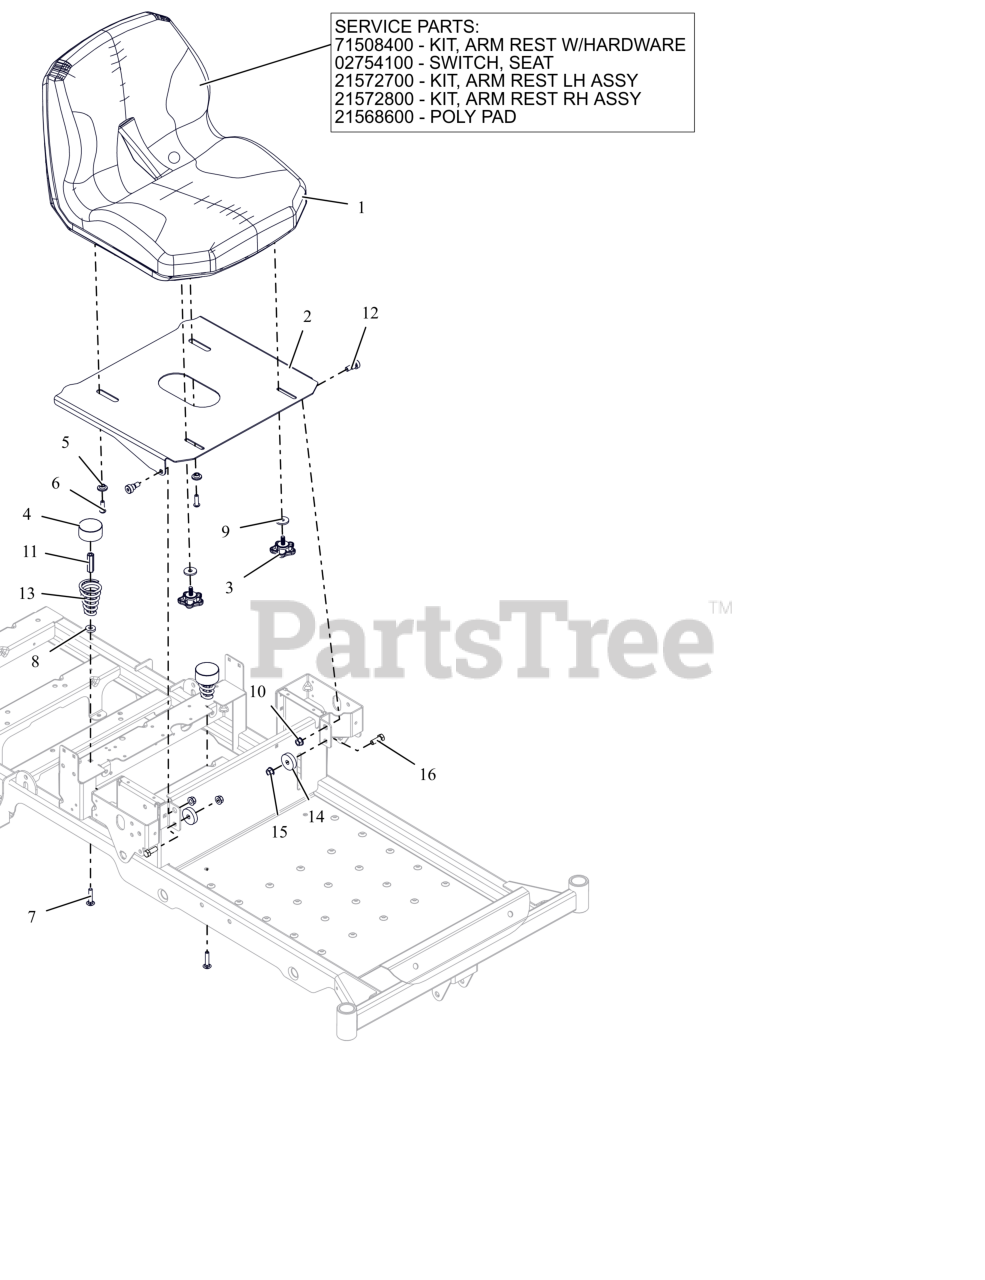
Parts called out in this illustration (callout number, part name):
1	SEAT, EDGE 2020
1	KIT, ARMREST - EDGE
1	SWITCH- SNAP MTG N.O.
1	KIT, ARM REST LH ASSY - PADDED
1	KIT, ARM REST RH ASSY - PADDED
1	POLY PAD
2	PLATE, SEAT (ORANGE)
3	KNOB, WING STUDDED
4	HUB CAP
5	BSHG-FLG .32X.500X.344X.880
6	BLT,SHCS-BTN .31-18X1.00 ZCC
7	BLT,RHSN .31-18X1.50 G5 ZCC
8	WSHR, FLT .328X.870X.179 ZCC
9	WSHR, FLT .340X1.125X.135 ZCC
10	NUT-LK-TOP-FLG .38-16 ZC120
11	NUT, COUPLING .31-18X1.75 ZCC
12	BLT-SHLDR .38-16X.38 SKH
13	SPRING, SEAT
14	SPACER, .39 X 1.50 X .380
15	NUT-LK-CTR-FLG .375-16 GF ZCC
16	BLT,HEX .38-16X1.00 G5 ZCC
